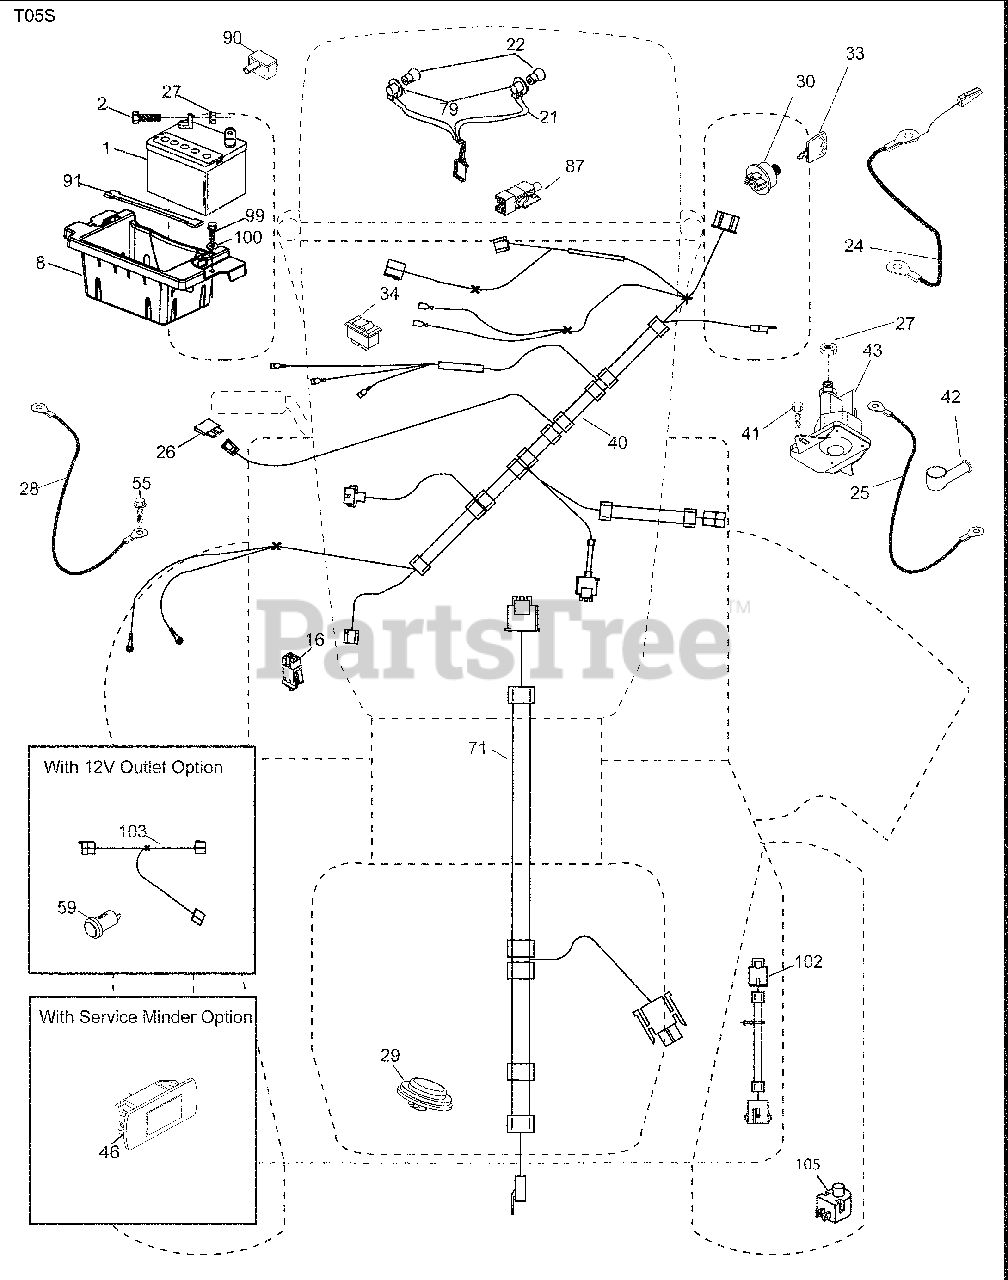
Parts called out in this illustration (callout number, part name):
1	Battery
2	Bolt Hex Head 1/4-20 x 3/4
8	Box Tray
16	Switch Interlock Push-In
21	Harness Socket Light w/4152J
22	Bulb Light
24	Cable Battery
25	Cable Starter
27	Nut Keps Hex 1/4-20 unc
28	Cable, Ground
29	Switch, Seat
30	Switch, Ign
33	Key/Chain
34	Switch Light/Reset
40	Harness Ign. Dash
41	Screw Thd Cut 1/4-20 x 1/2
42	Cover, Terminal
43	Solenoid
46	Gauge Serviceminder Hrmtr
55	Screw Thdrol 5/16-18 x 3/4 TYTT
71	Harness Ign. Chassis
79	Socket Asm. Bulb
87	Switch Interlock
90	Cover Terminal
91	Strap Battery
99	Screw 1/4-20 x 3/4
100	Washer 9/32 x 7/8 x 16 Ga.
102	Harness Pigtail
105	Switch Reverse
